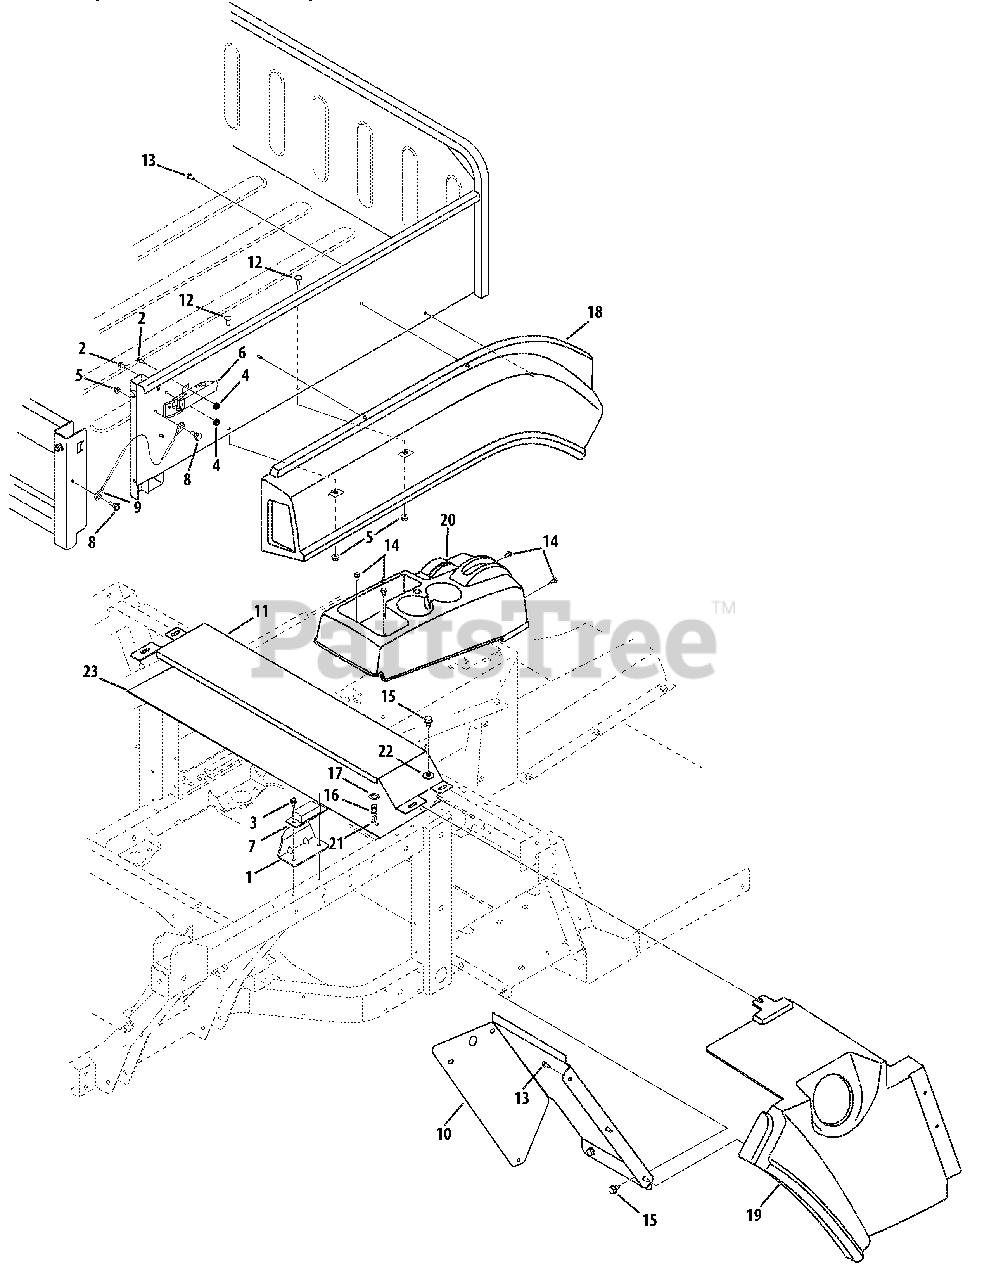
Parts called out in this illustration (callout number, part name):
1	Brkt, Bed Guide
2	Scr, mach, #10-24, 0.500, trusphi
3	Scr, tt, 1/4-20x.625, hxindwsh
4	Nut, hexlk, #10-24, gr2, nylon
5	Nut, flglk, 1/4-20, grf, nylon
6	Latch, draw, over Center
7	Bmpr, suspn, extn
8	Scr, shldr, .375x.280, 1/4-20
9	Cbl, lanyard
10	Brkt, Rh, Shld
12	Scr, Crg, 1/4-20, .62, Gr2
13	Scr, #12-16, .50, Hxindwsh
14	Scr, Tt, 1/4-20, 0.500
15	Scr, Tt, 5/16-18, 0.500
16	Spr, Comprs, .40 OD X .040 Dia.
17	Latch, Pnl, 1/4 Turn
18	Fdr, Rh Rr
18	Fdr, Rh Rr, Camo
19	Fdr, Lwr Rh Rr
19	Fdr, Lwr Rh Rr Camo
20	Cnsol, Seat
20	Cover, Shaft, Bench Seat
21	Spr, Clip
22	Washer, Bell, .340 x .872 x .060
23	Insl., CVR, UV
